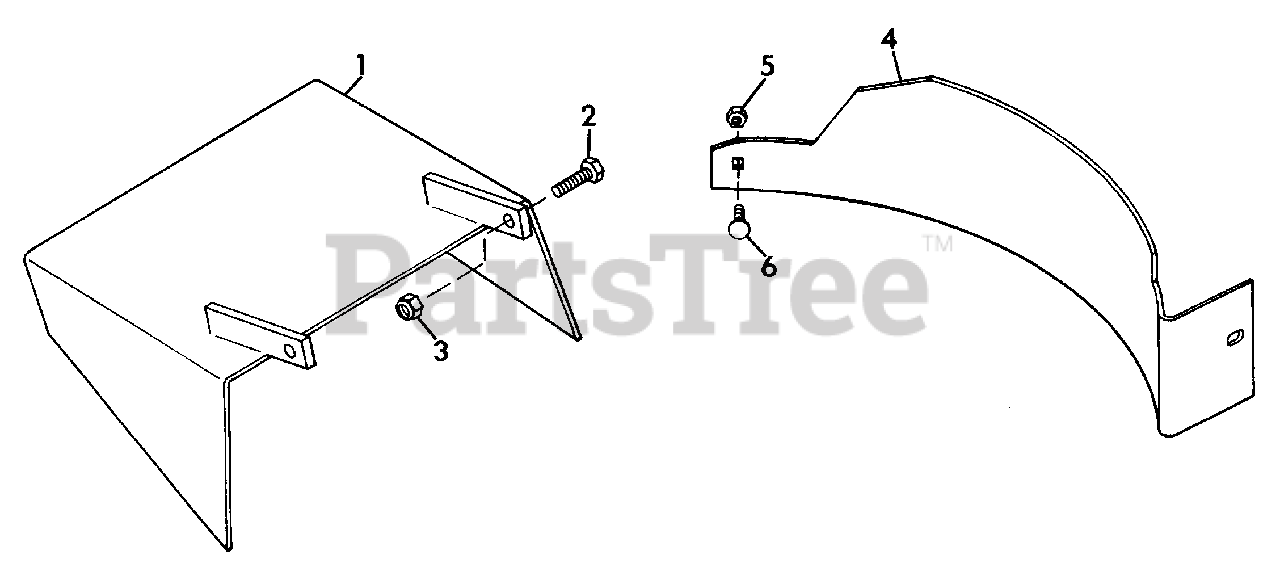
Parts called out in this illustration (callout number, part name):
1	WELDMENT, DISCHARGE CHUTE
2	BOLT, HEX 5/16-18X1.25
3	NUT, LOCK 5/16-18
4	BAFFLE
5	NUT, LOCK 1/4-20
63	BOLT, 1/4-20X.75 RD HD SQ NK
